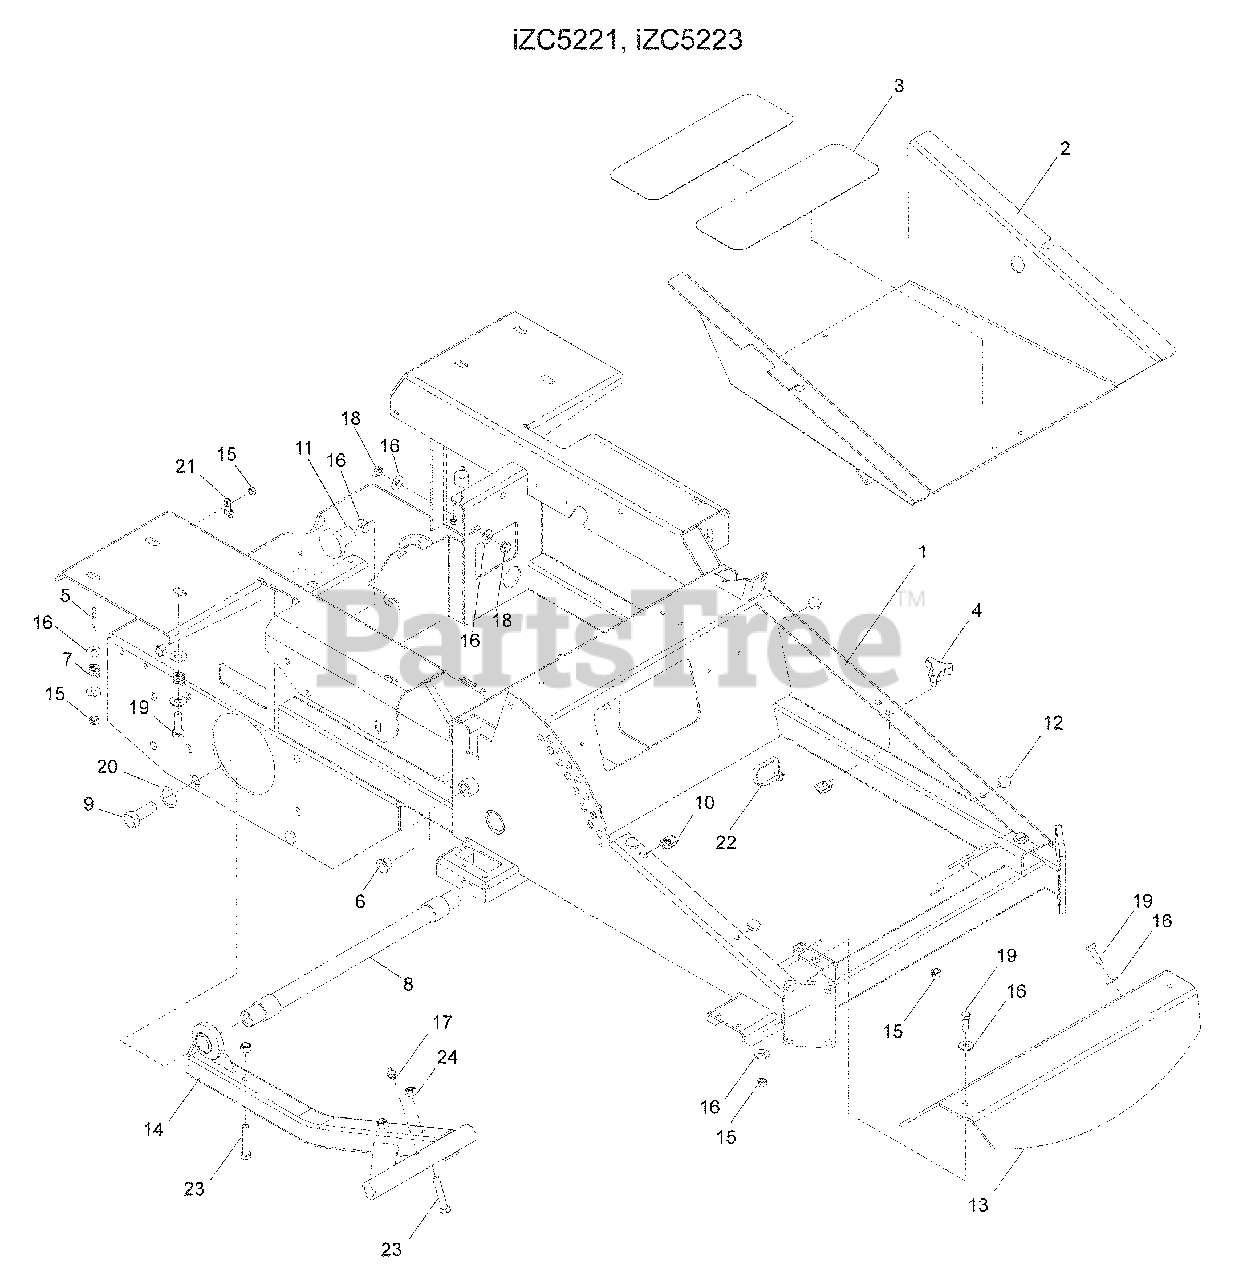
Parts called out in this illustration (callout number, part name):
1	FRAME w/DECALS
2	FOOT PLATE w/DECALS
3	PAD, ABRASIVE
4	KNOB w/STUD
5	TANK-STUD FUEL
7	SPRING, FUEL TANK
8	STRUT MOUNT
9	HCS 5/8-11 x 2
10	NUT 5/16-18, U-TYPE
12	GROMMET, BUMPER
15	NUT 5/16-18 HEX NYLOC
16	WASHER 5/16 STD FLT
17	ZERK, STRAIGHT ¼-28
18	NUT 5/16-18 HEX CTRLK
19	HCS 5/16-18 x 1
20	WASHER 5/8 SPLIT LOCK
21	CLAMP, DOUBLE TUBE
22	TIE, PLASTIC
23	HCS 3/8-16 x 2
24	NUT 3/8-16 HEX NYLOC
